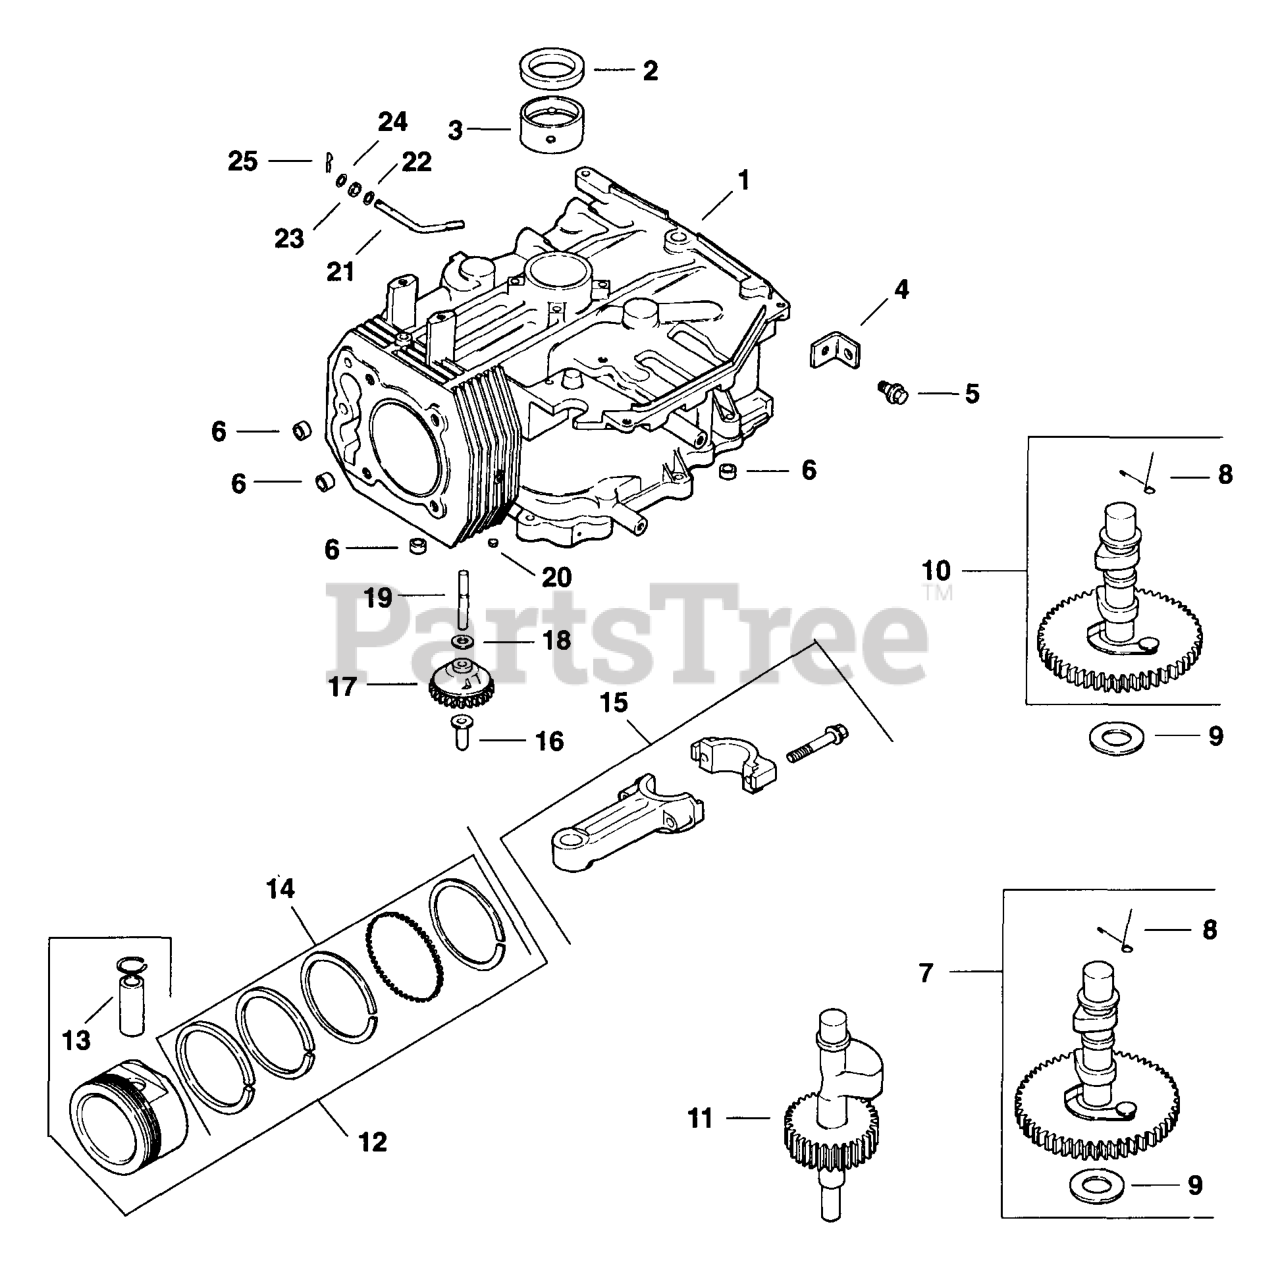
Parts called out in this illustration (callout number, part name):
1	Crankcase
2	SEAL, OIL
3	BEARING-(#DSC)
3	BEARING .25mm
3	BEARING .50mm
5	SCREW - USE M-839025
6	PIN - USE 12 380 17
8	SPRING - USE 12 089 31
9	SHIM, CAMSHAFT (YELLOW .034")
9	SHIM, CAMSHAFT (RED .032")
9	SHIM, CAMSHAFT (BLACK .04")
9	SHIM, CAMSHAFT (WHITE .028")
9	SHIM, CAMSHAFT (BLUE .03")
9	SHIM, CAMSHAFT (GREEN .036")
9	SHIM, CAMSHAFT (GRAY .038")
10	CAMSHAFT - USE 12 010 12
11	SHAFT - USE 12 144 19
12	KIT, PISTON W/RING SET (STD) - DISCONTINUED
12	KIT, PISTON W/RING SET (.25) - DISCONTINUED
12	KIT, PISTON W/RING SET (.50)
14	RING SET (STD.)
14	RING SET (.25)
14	RING SET (.50)
15	ROD - USE 12 067 05
15	ROD - USE 12 067 06
16	PIN, GOVERNOR REGULATING
17	GOVERNOR GEAR ASSEMBLY
18	Washer, governor gear thrust
19	SHAFT, GOVERNOR GEAR
20	PLUG, CUP
21	KIT - USE 12 755 64
22	WASHER, FLAT 1/4"
23	SEAL, GOVERNOR CROSS SHAFT
24	Washer, governor shaft
